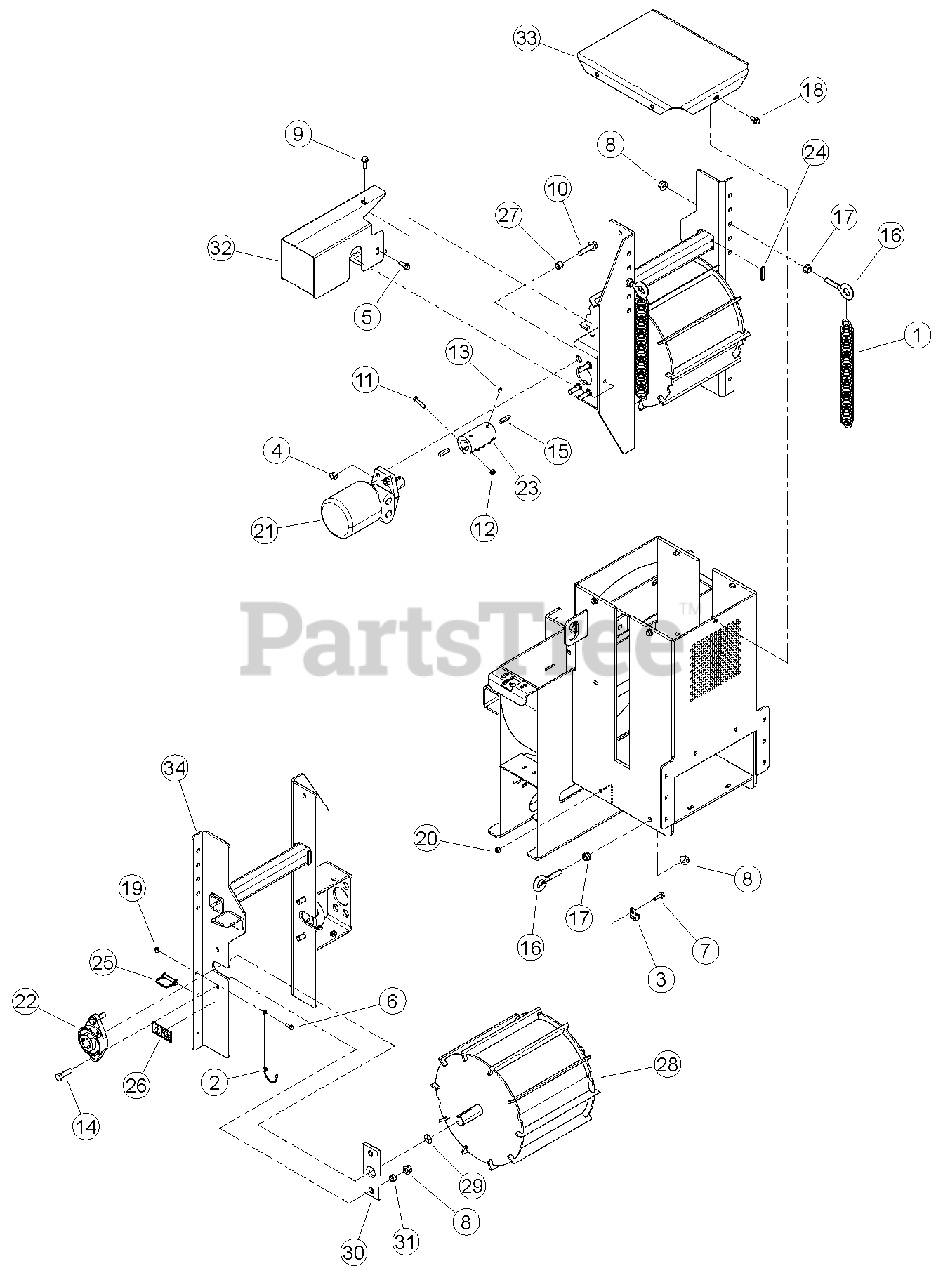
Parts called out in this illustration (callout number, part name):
1	SPRING, EXTENSION
2	LANYARD, NYLON
3	CLAMP, 9/16 COATED
4	NUT, 1/2" CENTERLOCK GRB ZP
5	SCREW, 3/8-16 X 1 T23 THD CUTT HWH MAGNI 565 SILVER
6	BOLT, 1/4-20 X 3/4 HWH GR5 CZP
7	BOLT, 5/16 X 1 FLANGE NC
8	NUT, 1/2-13 NYLOCK FLANGE
9	BOLT, 3/8 X 1 FLANGE NC
10	BOLT, 1/2-13 X 2 HWH GR5 CZP
11	BOLT, 5/16 X 1-1/2 GR5 HEX CPS ZP
12	NUT, 5/16" NE NYLOCK ZP
13	SET SCREW, 3/8 X 1/2 CUP PT SKT
14	BOLT, 1/2 X 1 3/4 GR5 HCPS NC ZP
15	KEY, 5/16 X 1-1/2 SQUARE
16	EYEBOLT, 1/2 X 2" ZP
17	NUT, 1/2 SPIRAL LOCK NC ZP
18	BOLT, 3/8 X 3/4" SERRATED FLANGE
19	NUT, 1/4-20 NYLOCK-FLANGE
20	NUT, 5/16-18 NYLOCK-FLANGE
21	MOTOR, 45 CU IN HYDRAULIC
22	BEARING, 1-1/4" DIA 2 BOLT FLANGE
23	COUPLER, 1-1/4 SHAFT
24	WEAR PAD, STD.SPRING HD FRONT
25	PIN, SNAP 3/8 X 1-1/2 USABLE LGH
26	DECAL, CRUSHING ISO
27	SPACER,0.75 X 0.620
28	ASSEMBLY, 6" FEED ROLLER SERVICE
29	DECAL, ROTATING SHAFT
30	BEARING, SLIDE
31	SPACER, .75 OD X .5 ID X .37
32	WELDMENT, MOTOR COVER
33	WELDMENT, TOP ROLLER COVER
34	WELDMENT, ROLLER SLIDE
